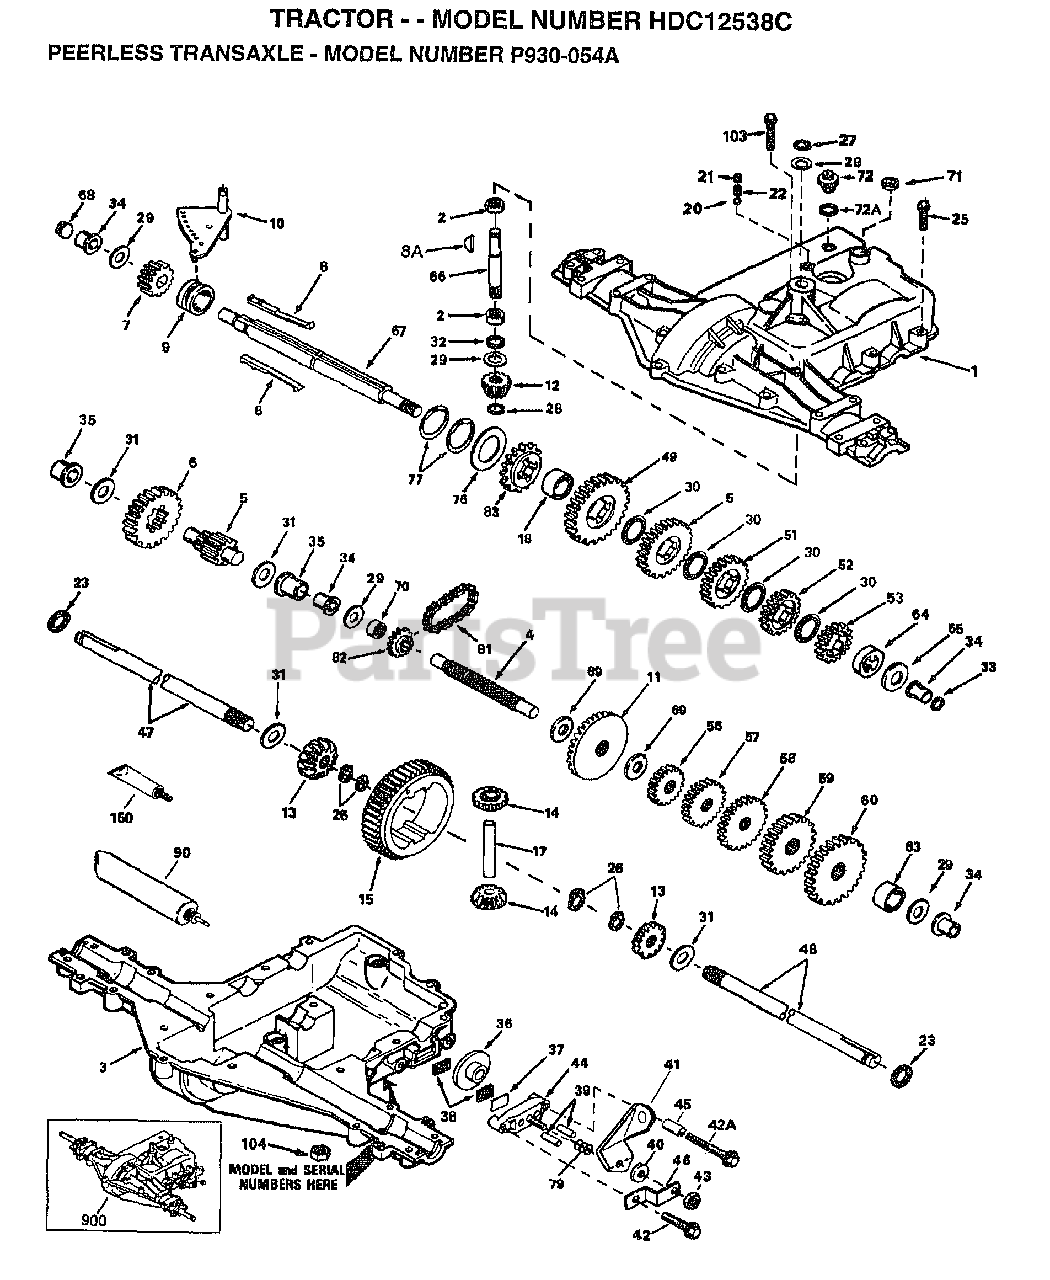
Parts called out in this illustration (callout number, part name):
1	TRANSAXLE COVER
2	BEARING, NEEDLE
3	TRANSAXLE CASE
4	SHAFT, COUNTER
5	OUTPUT SHAFT AND PINION
6	GEAR, OUTPUT
7	GEAR, SPUR, 15 TEETH
8A	KEY, WOODRUFF
9	COLLAR, SHIFTER
10	ROD & FORK ASSY, SHIFT
11	GEAR, BEVEL, 42 TEETH
12	BEVEL PINION, INPUT
13	GEAR, BEVEL
14	GEAR, BEVEL, PINION
18	SPACER, NEUTRAL
20	BALL STEEL, 5/16" DIA.
21	SCREW, 3/8-16 X 3/8"
25	SCREW, 1/4-20 X 1-1/4
26	RING RETAINER
27	RING, RETAINER
28	RETAINING RING
29	WASHER THRUST
30	WASHER THRUST
33	SEAL, SQUARE CUT
34	BUSHING, FLANGED
35	BUSHING, FLANGED
36	DISK, BRAKE
37	PLATE BRAKE PAD
41	BRAKE LEVER
42	SCREW, 1/4-20 X 1-1/4
42A	SCREW, 1/4-20 X 2-1/4
43	LOCKNUT 5/16-24
44	HOLDER BRAKE PAD
46	BRKT BRAKE LEVER
49	GEAR, SPUR, 37 TEETH
50	GEAR, SPUR, 30 TEETH
51	GEAR, SPUR, 25 TEETH
52	GEAR, SPUR, 22 TEETH
53	GEAR, SPUR, 19T
56	GEAR, SPUR, 12 TEETH
57	GEAR, SPUR, 20 TEETH
58	GEAR, SPUR, 25 TEETH
59	GEAR, SPUR, 28 TEETH
60	GEAR, SPUR, 31 TEETH
65	WASHER, THRUST
66	SHAFT, INPUT
67	SHAFT, BRAKE, 4 KEYED
69	WASHER THRUST
71	SEAL SQUARE CUT
72	THREADED PLUG 9/16-18
76	WASHER, THRUST
77	INVERTED RETAINING RING
81	CHAIN, ROLLER
82	SPROCKET 9T
83	SPROCKET 18T (REV)
90	GREASE BENTONITE, 32 OZ.
150	GASKET ELIMINATOR
900	REPLACEMENT TRANSAXLE
